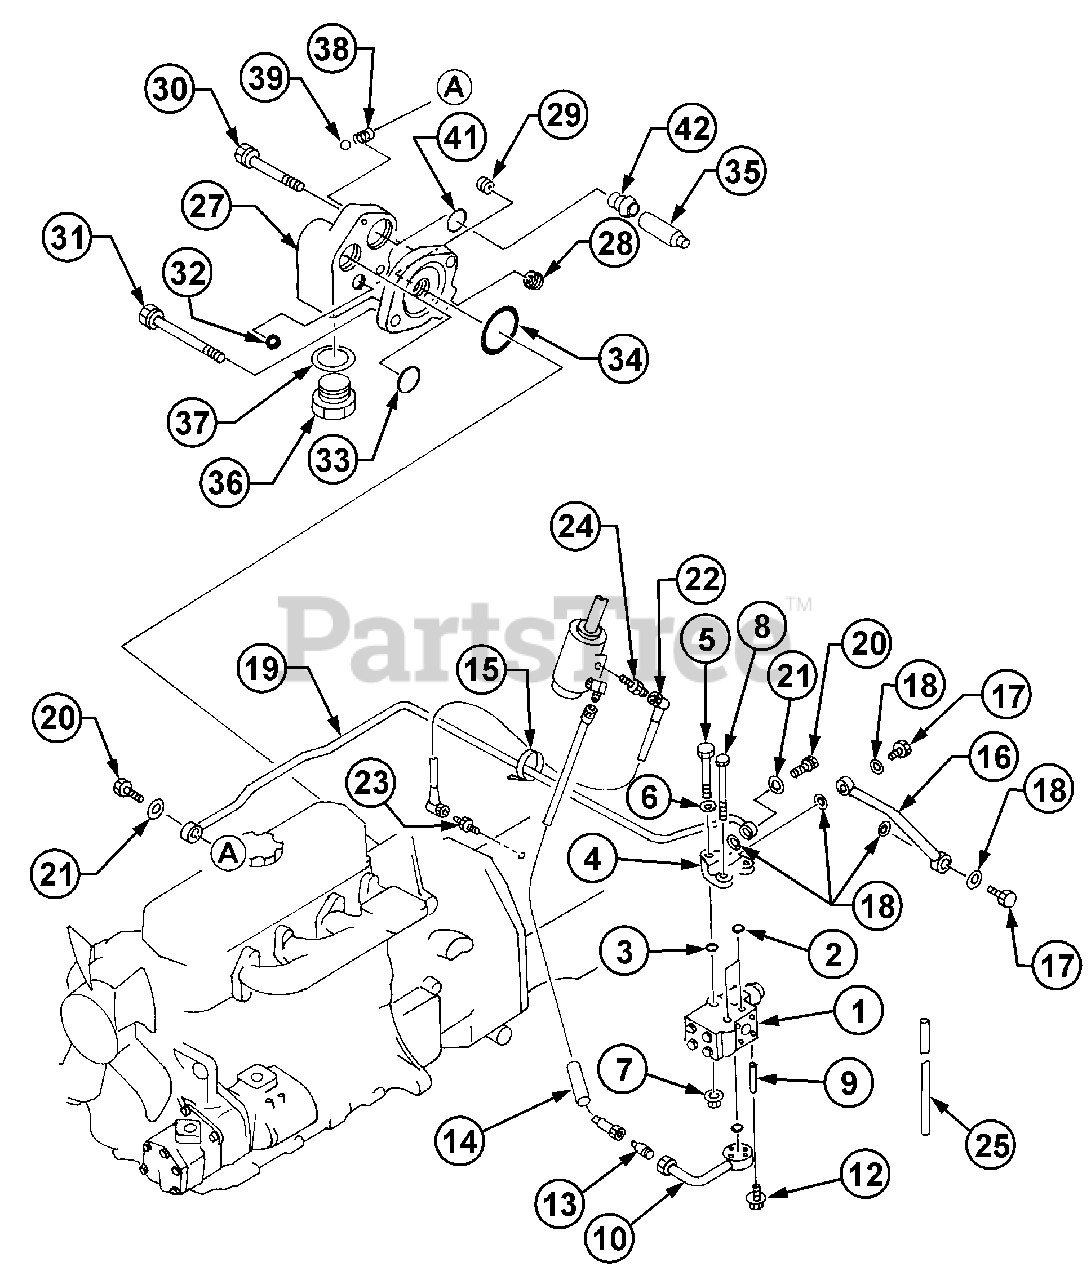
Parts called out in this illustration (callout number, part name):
1	Flow Divider Valve
18	Washer, Seal
21	Washer, Seal
32	O-Ring
